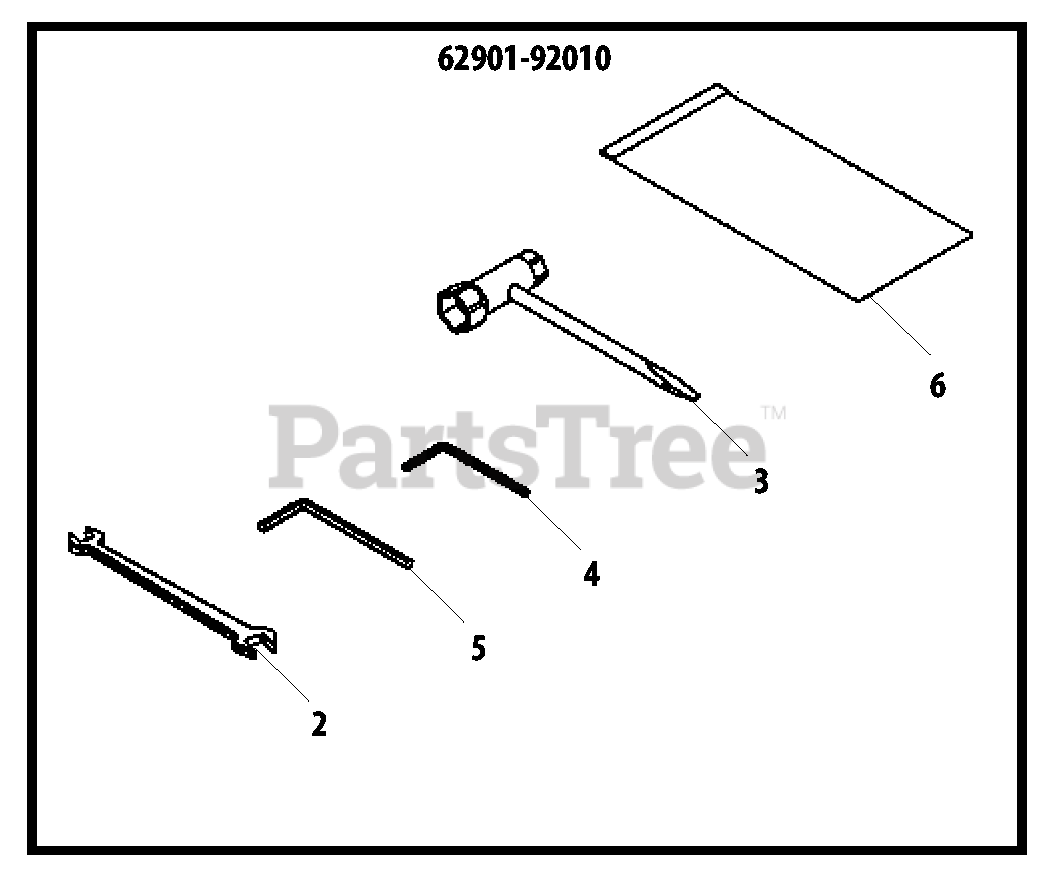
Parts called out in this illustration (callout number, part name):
2	SPANNER - 8X10mm
3	T-WRENCH - 13X16mm
4	HEX KEY - 3mm
5	HEX KEY - 4mm
6	BAG, TOOL
62901-92010	TOOL KIT
